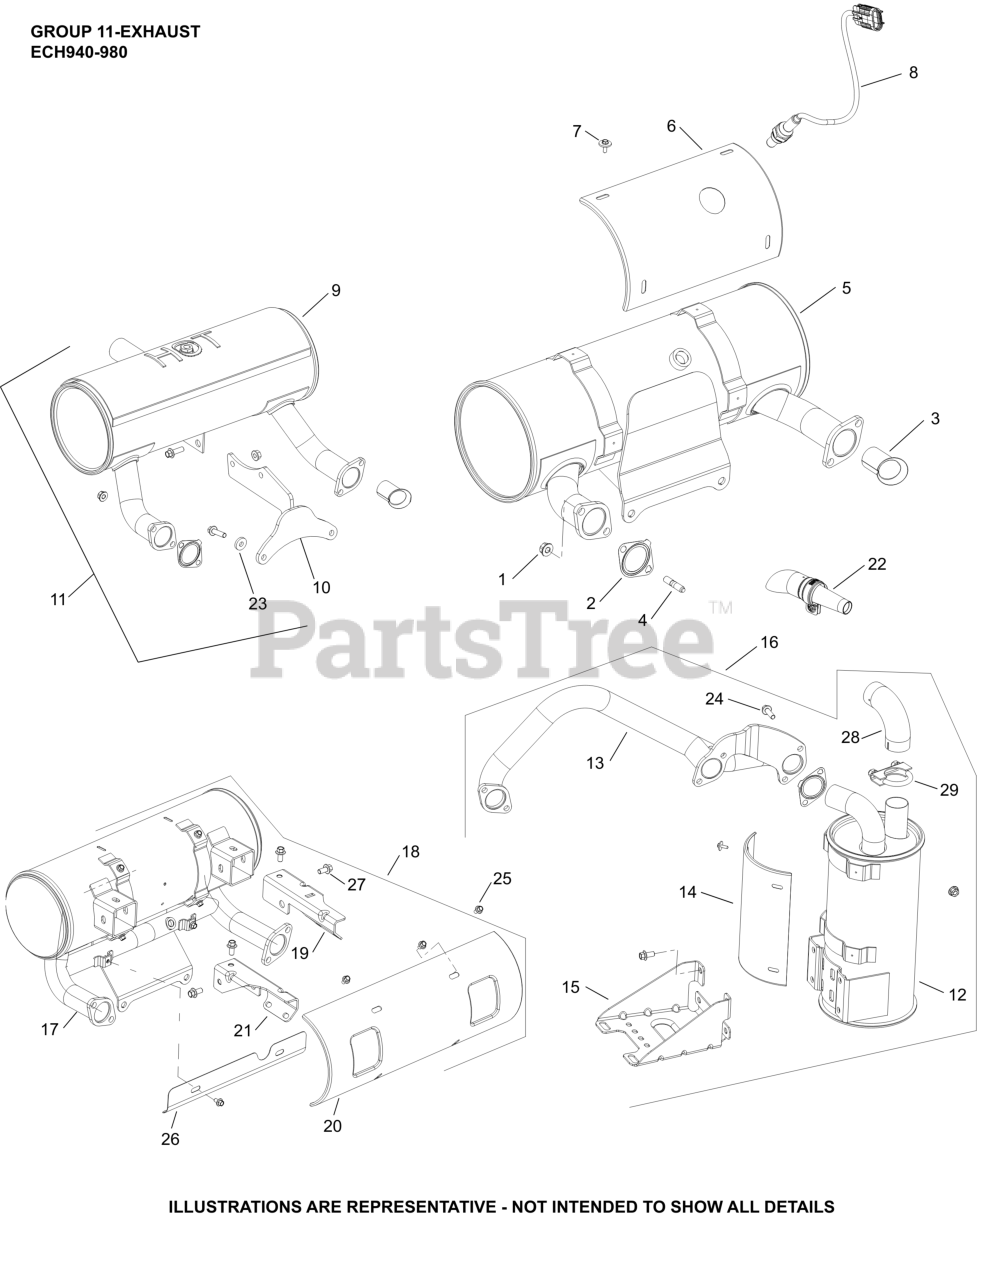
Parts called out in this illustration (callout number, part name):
1	NUT, HEX FLANGE LOCK (M8)
2	GASKET, EXHAUST
3	LINER, EXHAUST PORT
4	STUD, METRIC EXHAUST
18	SENSOR, OXYGEN (M18 x 1.5 THREADS)
